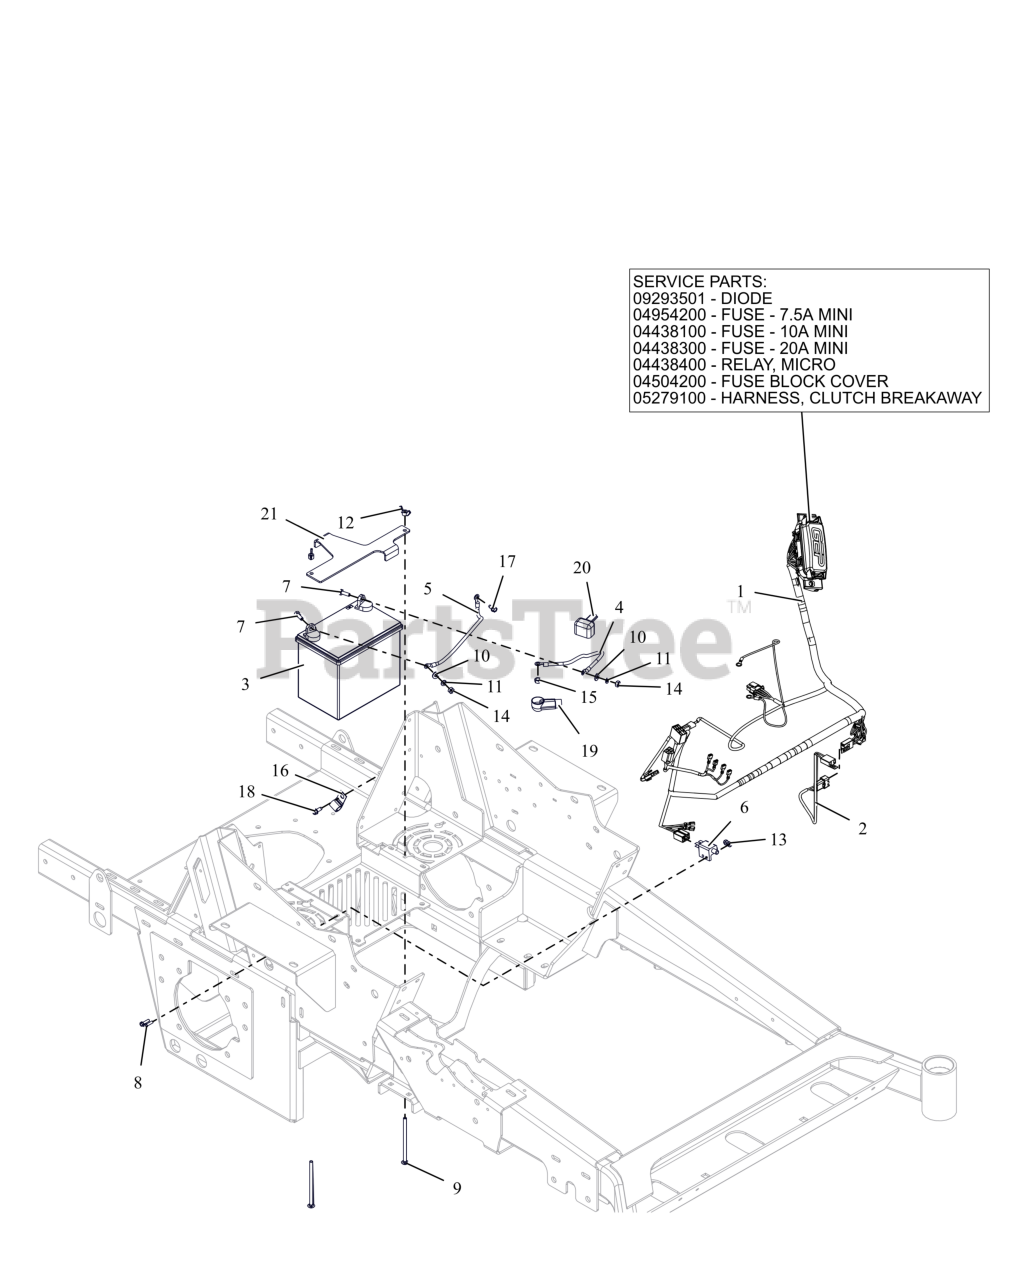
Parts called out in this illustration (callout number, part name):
1	HARNESS- WIRE PT300 MAIN
1	DIODE, CONNECTOR SHELL
1	FUSE, 7.5 AMP MINI-ATC
1	FUSE,10 AMP MINI-ATC
1	FUSE,20 AMP MINI ATC
1	RELAY,MICRO5 TERML W/RESISTOR
1	COVER, HARNESS FUSE/RELAY MOD
1	HARNESS, CLUTCH BREAKAWAY
2	HARNESS- PT300 SEAT JUMPER
3	BATTERY, 300 CCA 10U1L
4	CABLE, STARTER 13.00"
5	CABLE-GROUND .25 X 13.00 X .31
6	SWITCH- DOUBLE POLE N.O./N.O.
7	BLT, HEX .25-20X.75 G5 ZCC
8	BLT, HWH #10-24X.75 ZCC
9	BLT, RHSN .25-20X4.50 G5 ZCC
10	WSHR,FLT .281X.625X.065 ZCC
11	WSHR,LK-REG .250X.062 ZCC
12	NUT, LK-WING .25-20 ZCC
13	NUT-LK-NYL #10-24 G2 ZCC
14	NUT-STD .250-20 G2 ZCC
15	NUT-HEX-JAM-CTR LK M8X1.25 ZCC
17	SCR-TAP .25-20X.50 HWH ZCC
18	SCR,TAP .25-20X.625 HWH ZCC
19	BOOT, .65ID POS
20	INSULATOR
21	HOLDDOWN- BATTERY
